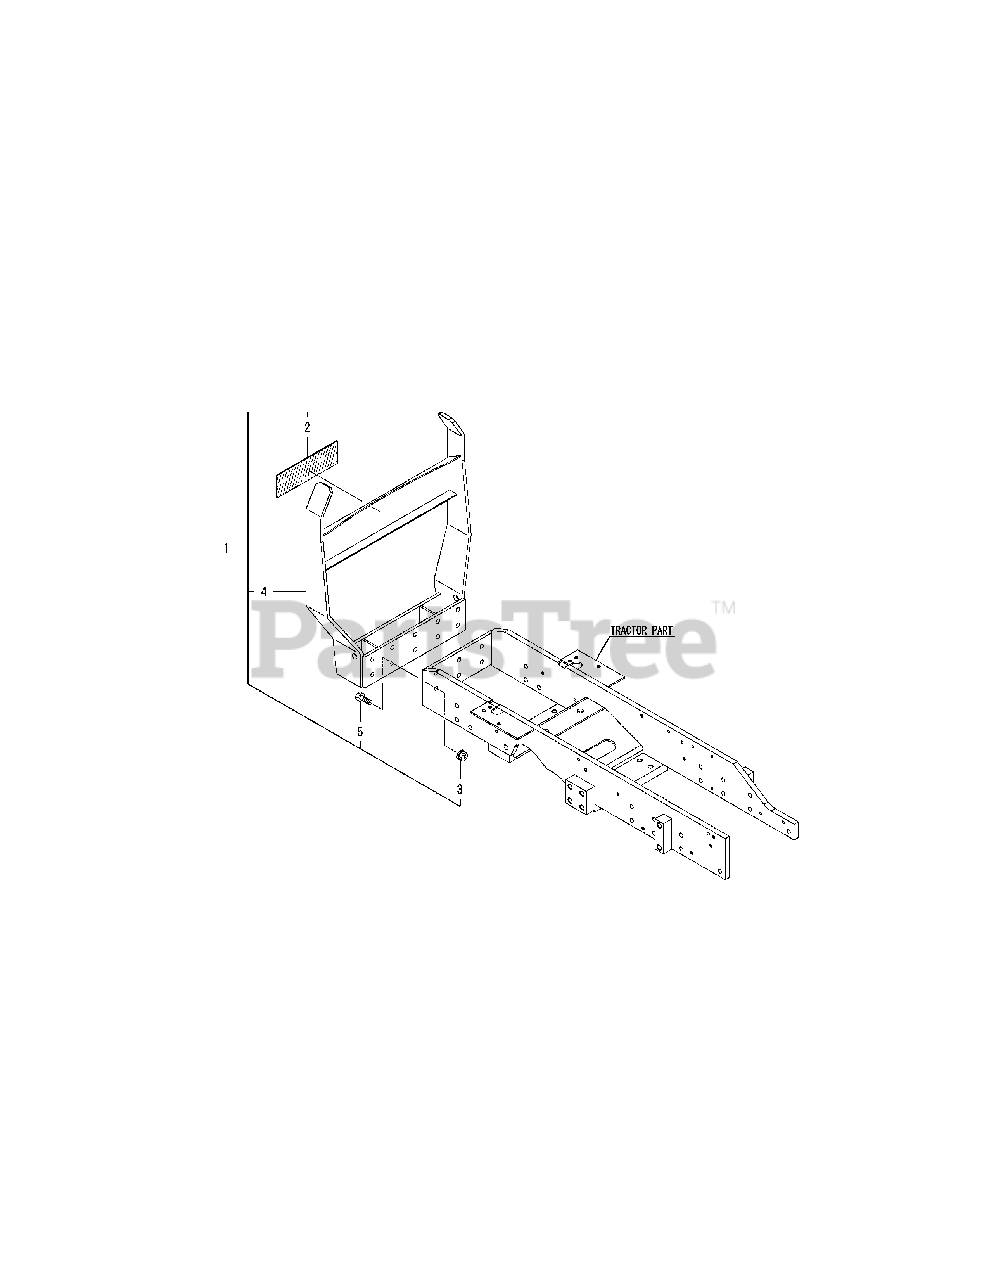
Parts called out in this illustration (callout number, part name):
1	GRILLE GUARD KIT
2	LABEL, GRILL GAURD
3	NUT W/WASHER 12
4	GRILLE GUARD CMP
5	BOLT M12X 35 PLATED
